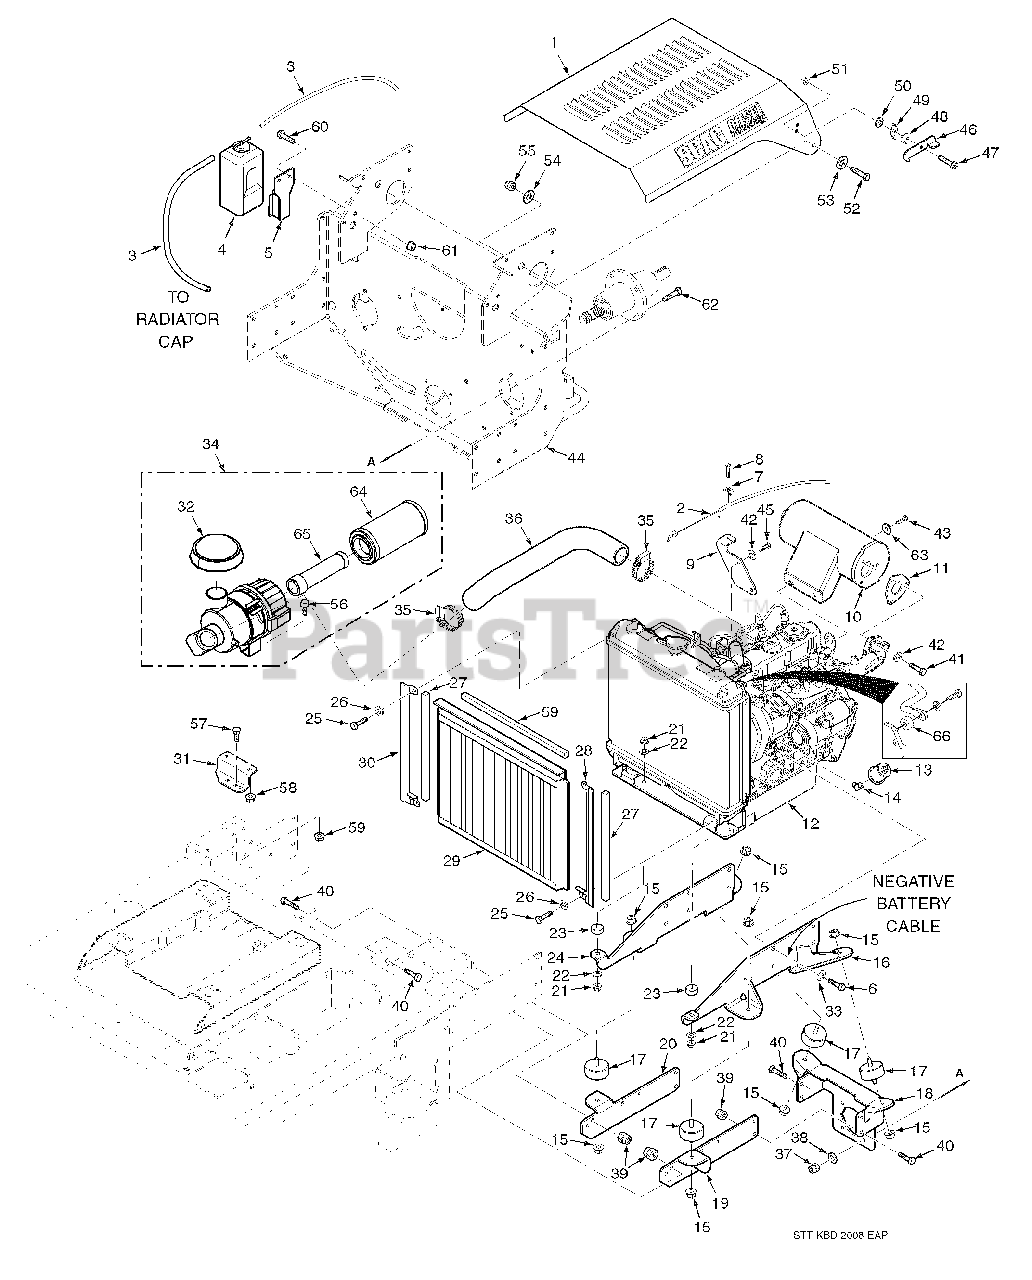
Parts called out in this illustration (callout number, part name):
1	Hood Assembly
2	Throttle Cable
3	Hose, Over Spill Bottle
4	Over Spill Bottle
5	Mounting Bracket, Over Spill Bottle
6	Bolt, Metric Hex Head M10-1.25 x 25LG
7	Clamp
8	Screw, Self Tapping
9	Bracket, Control Mount
10	Muffler, Kubota
11	Gasket, Muffler
12	Engine, Kubota
13	Oil Pressure Sender
14	Elbow, 45 Degree
15	Nut, Serrated Flange 5/16-18
16	Mounting Bracket Weldment LH
17	ISO Mount
18	Plate, Rear Engine Mount
19	Plate, Engine Mount LH
20	Plate, Engine Mount RH
21	Nut, Metric Hex M8-1.25
22	Lockwasher, 5/16" Spring
23	Rubber ISO Mount, Radiator
24	Mounting Bracket Weldment RH
25	Capscrew, Metric M6-1.0 x 16
26	Lockwasher, 1/4" Spring
27	Foam, Radiator Screen
28	Debris Screen Track LH
29	Debris Screen Assembly
30	Debris Screen Track RH
31	Bracket, Air Cleaner Mount
32	Rain Cap
33	Lockwasher, 7/16" Spring
34	Air Filter Assembly
35	Clamp, 2-1/4" Max. Dia.
36	Hose, Air Intake
37	Nut, Elastic Stop 5/16-18 Grade 8
38	Lockwasher, 5/16" Spring
39	Nut, Elastic Stop 3/8-16
40	Bolt, Hex Head 3/8-16 x 1"
41	Bolt, Metric Hex Head M8-1.25 x 30LG
42	Lockwasher, 5/16" Spring
43	Bolt, Metric Hex Head M8-1.25 x 25LG
44	Pump Mounting Plate Weldment
45	Bolt, Metric Hex Head M8-1.25 x 20LG
46	Latch, Hood
47	Bolt, Shoulder 5/16-18 x 1/2"
48	Spring, Hood Latch
49	Lock, Hood Latch
50	Flatwasher, 3/8-.391 x .938 x .105
51	Nut, Center Lock 5/16-18
52	Bolt, Hex Head 3/8-16 x 1-3/4"
53	Flatwasher, 3/8-.391 x .938 x .105
54	Flatwasher, 3/8-.406 x 1.50 x 7 Gauge
55	Nut, Elastic Stop 3/8-16
56	Bolt, Hex Head Serr. Flange 5/16-18 x 3/4"
57	Bolt, Carriage 5/16-18 x 3/4"
58	Nut, Serrated Flange 5/16-18
59	Foam, Radiator Screen Upper
60	Bolt, Hex Head Serr. Flange 5/16-18 x 3/4"
61	Nut, Serrated Flange 5/16-18
62	Bolt, Hex Head 5/16-18 x 1-3/4" Grade 8
63	Flatwasher, SAE 5/16-.344 x .688 x .065
64	Air Filter, Outer
65	Air Filter, Inner
66	Spacer, Radiator
